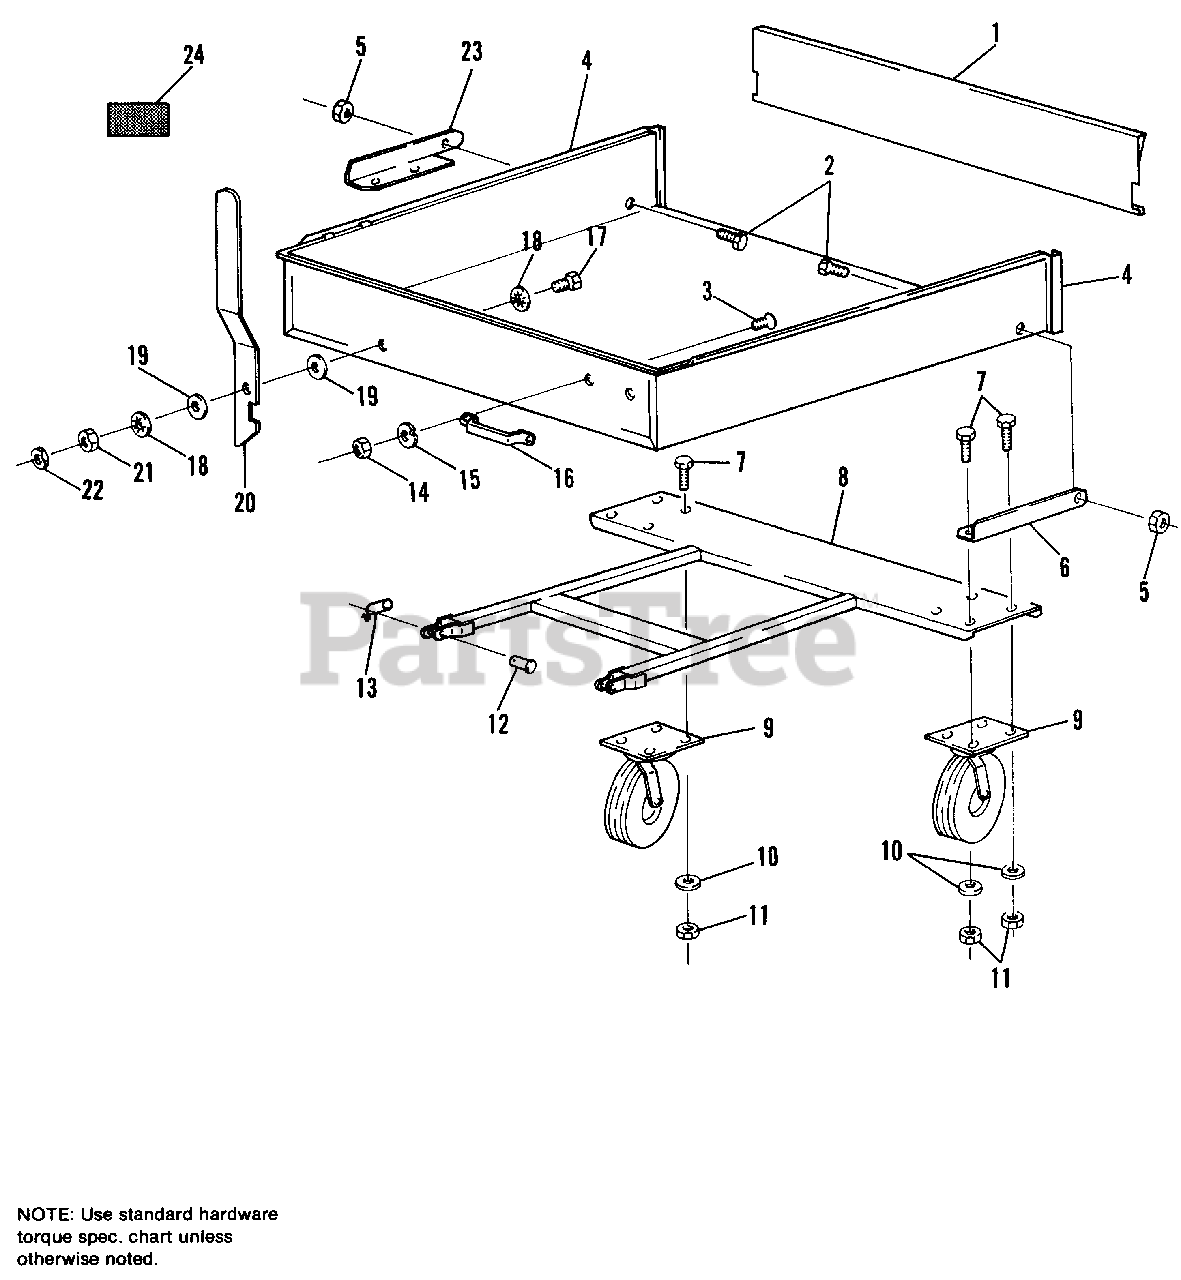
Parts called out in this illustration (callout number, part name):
2	CAPSCREW, 1/2-13 x 1
3	CAPSCREW, Hex, 1/4-20 x 1/2
5	NUT, Hex, Lock, 1/2-13
6	BRACKET, Pivot, L.H.
7	CAPSCREW, Hex
9	WHEEL, Swivel
10	WASHER, 3/8
11	NUT, Hex, Lock, 3/8-16
12	PIN, Clevis, 1/2 x 1-1/2
13	PIN, Safety
14	NUT, Hex, 1/4-20
15	LOCKWASHER, 1/4
16	HANDLE, Lift
17	CAPSCREW, 5/16-18 x 1-1/4
18	WASHER, 5/16
19	WASHER, Spring, 5/16
20	HANDLE, Latch
21	NUT, Hex, Full, 5/16-18
22	NUT, Hex, Jam, 5/16-18
23	BRACKET, Pivot, R.H.
24	DECAL, Max. Capacity
